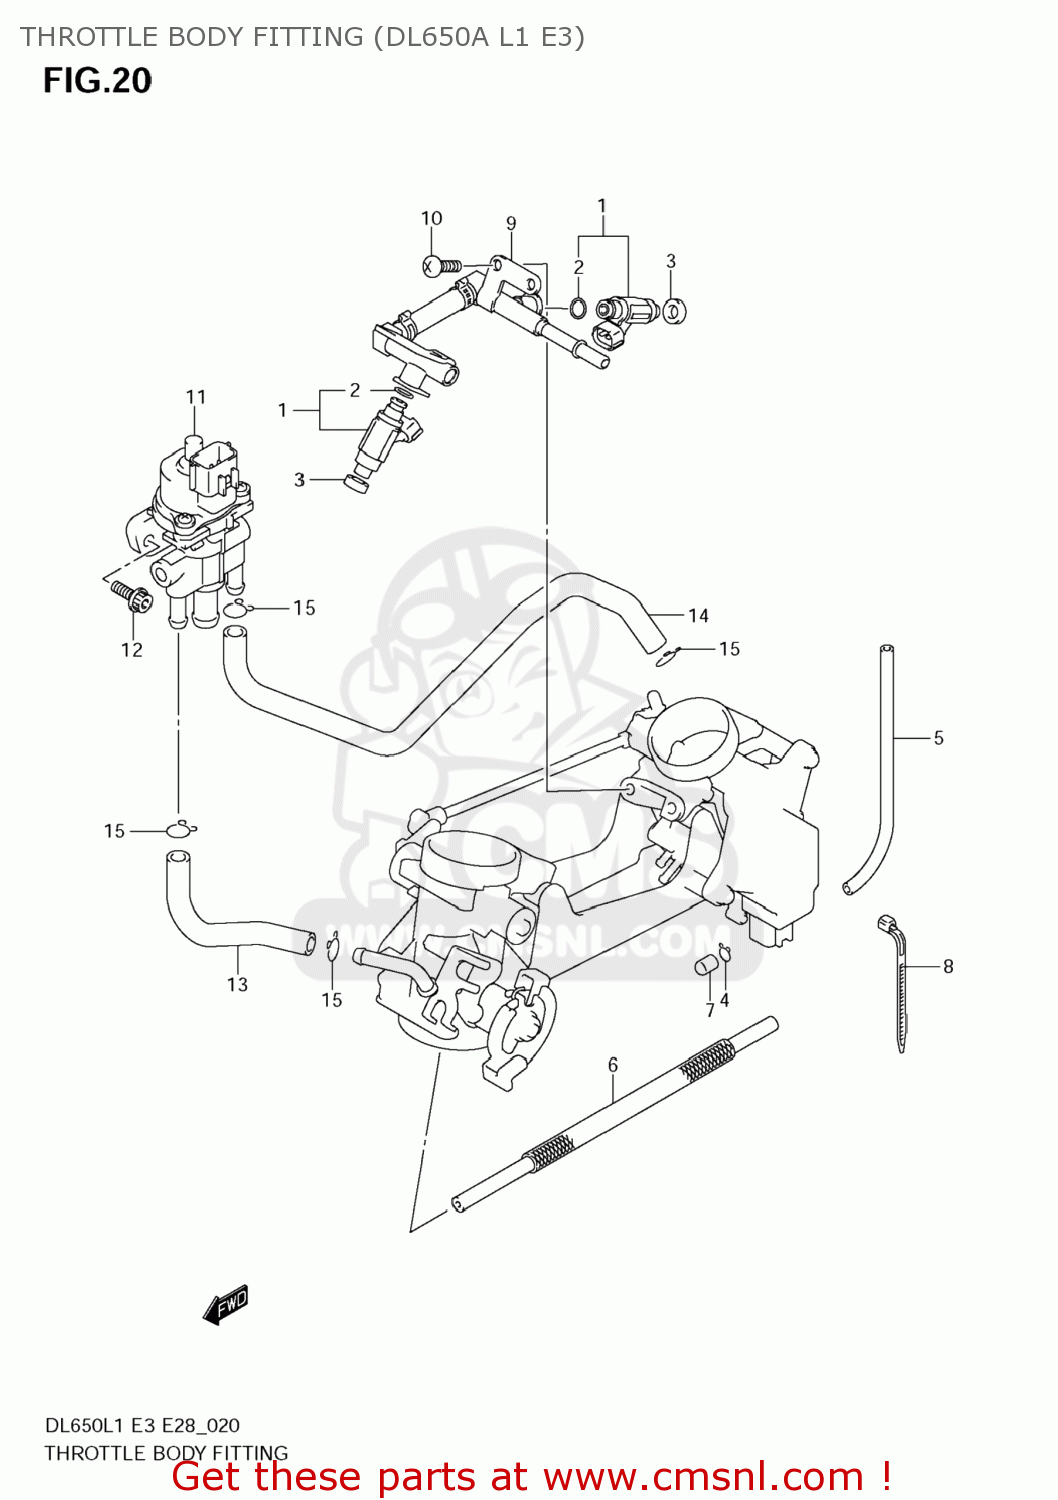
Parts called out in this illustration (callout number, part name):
1	INJECTOR ASSY
2	O RING
3	SEAL
4	CLIP
5	HOSE
6	HOSE
7	CAP
8	CLIP
9	DELIVERY PIPE ASSY
10	SCREW
11	VALVE,ISC
12	BOLT
13	HOSE,ISC VALVE FR
14	HOSE,ISC VALVE RR
15	CLIP
